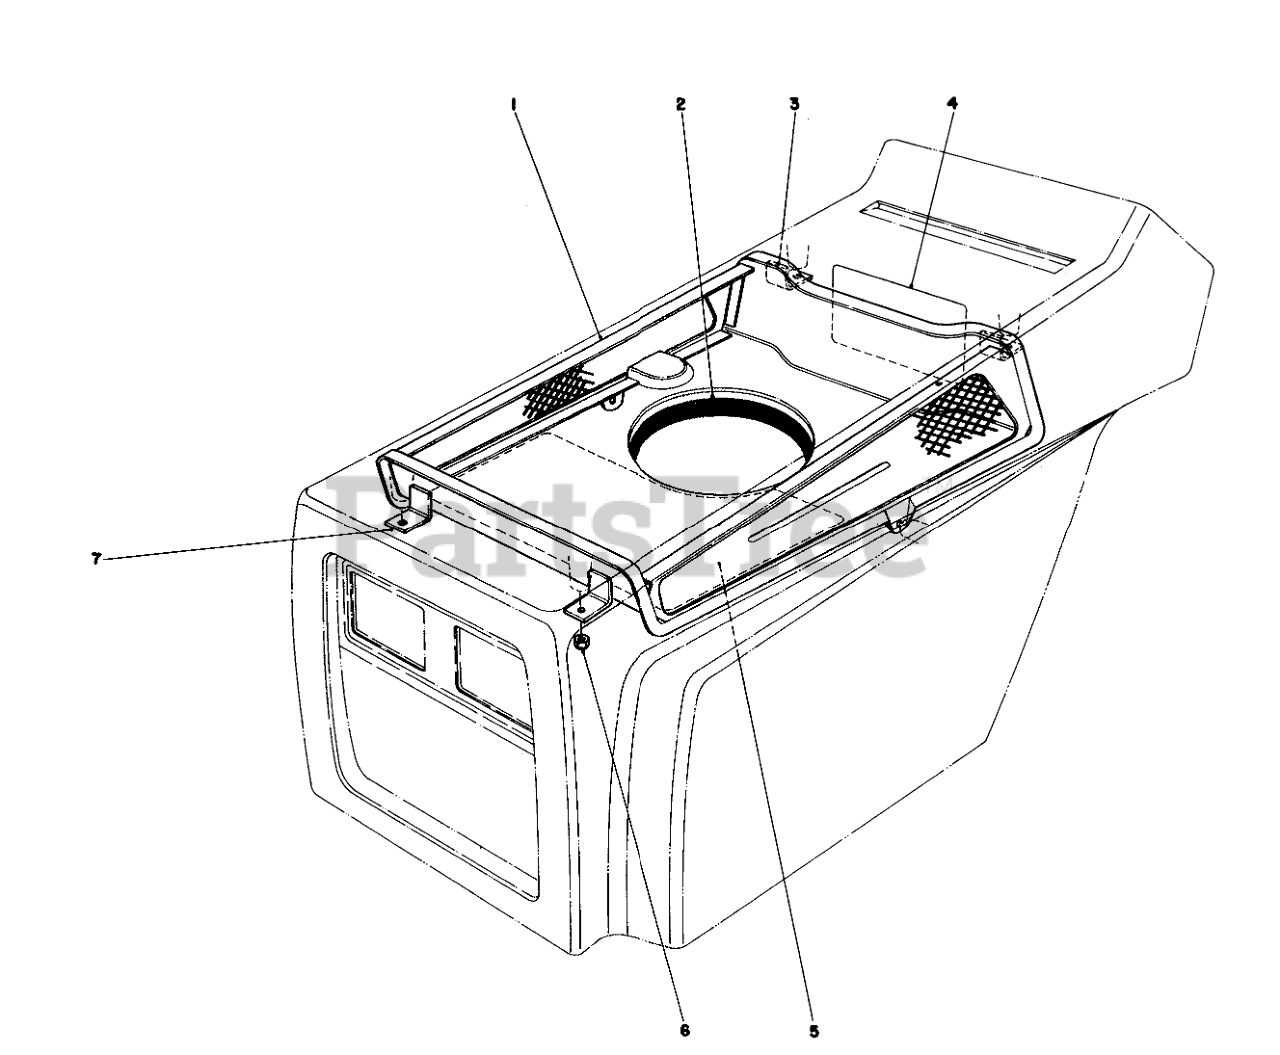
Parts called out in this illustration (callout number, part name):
1	Duct Hood
2	Seal Engine
3	Bracket Rear Duct Support
4	BELT DECAL
5	Decal Service
6	NUT-LOCK, CONE
7	Bracket Duct Support
